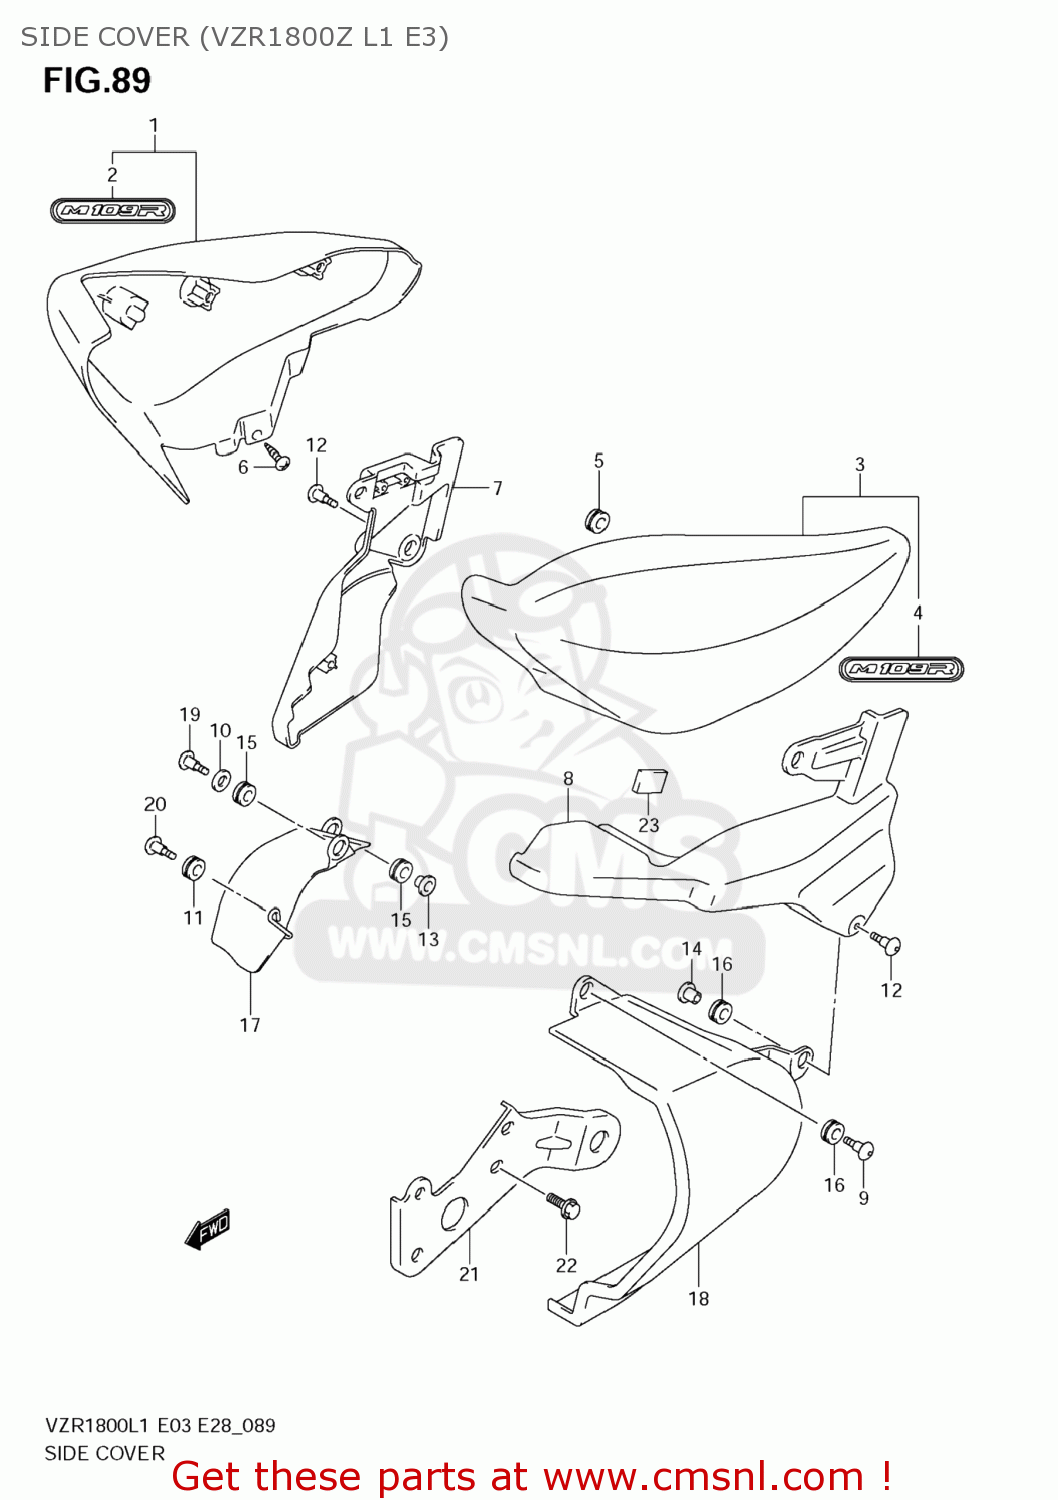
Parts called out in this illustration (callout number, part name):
1	COVER,SIDE,R(BLACK)
2	EMBLEM,M109R
3	COVER,SIDE,L(BLACK)
4	EMBLEM,M109R
5	CUSHION
6	SCREW
7	COVER,SIDE LWR,R
8	COVER,SIDE LWR,L
9	SCREW(6X20)
10	WASHER(10.5X20X2.3)
11	CUSHION
12	SCREW(6X25)
13	SPACER(6.5X10X11.6)
14	WASHER
15	CUSHION
16	CUSHION
17	COVER,LWR,R
18	COVER,LWR,L
19	SCREW(6X20)
20	SCREW(6X20)
21	BRACKET,LWR COVER,L
22	BOLT
23	CUSHION,FRAME COVER
